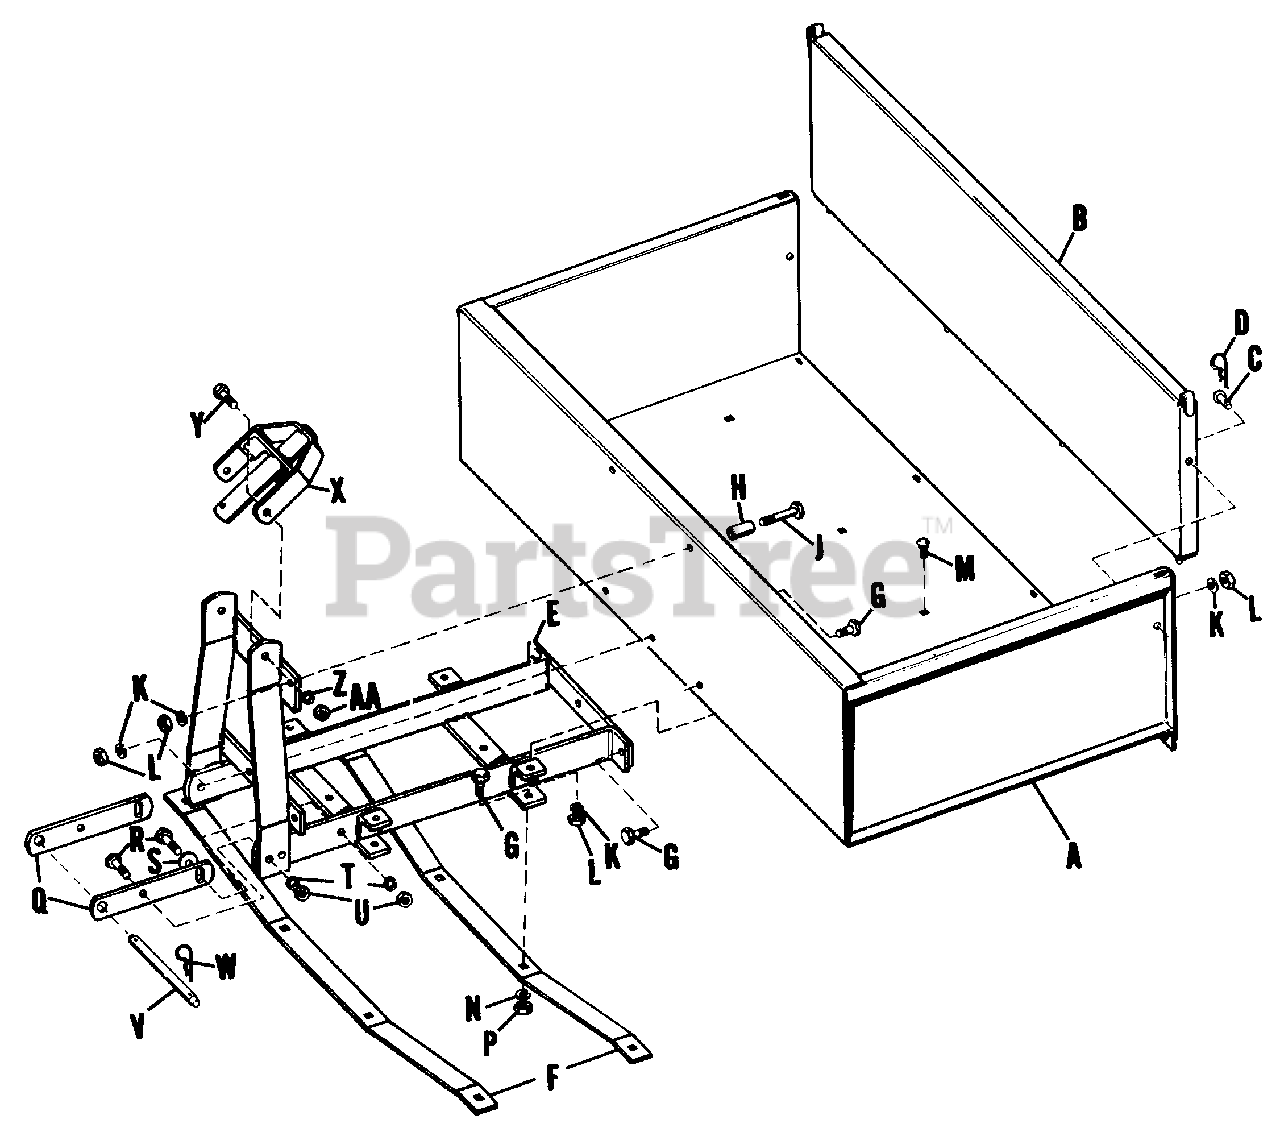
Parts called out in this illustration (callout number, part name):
A	Box, Carry-All
B	Gate, End
D	Clip, Spring
E	Frame Assembly, Box
G	Hex Capscrew, 5/16"-18 NC x 1" lg.
J	Hex Capscrew, 5/16-18 NC x 2" lg.
K	Lock Washer, 5/16"
L	Hex Nut, Full, 5/16"-18 NC
M	Carriage Bolt, 5/16"-18 NC x 3/4" lg.
N	Lock Washer, 5/16"
P	Hex Nut, Full, 5/16"-18 NC
R	Hex Capscrew, 3/8"-16 NC x 1 1/4" lg.
S	Washer, Plain
T	Lock Washer, 3/8"
U	Hex Nut, Full, 3/8"-16 NC
V	Pivot Rod
W	Clip, Spring
X	Bail Assembly
Y	Hex Capscrew, 3/8"-16 NC x 1" lg.
Z	Lock Washer, 3/8"
AA	Hex Nut, Full, 3/8"-16 NC
